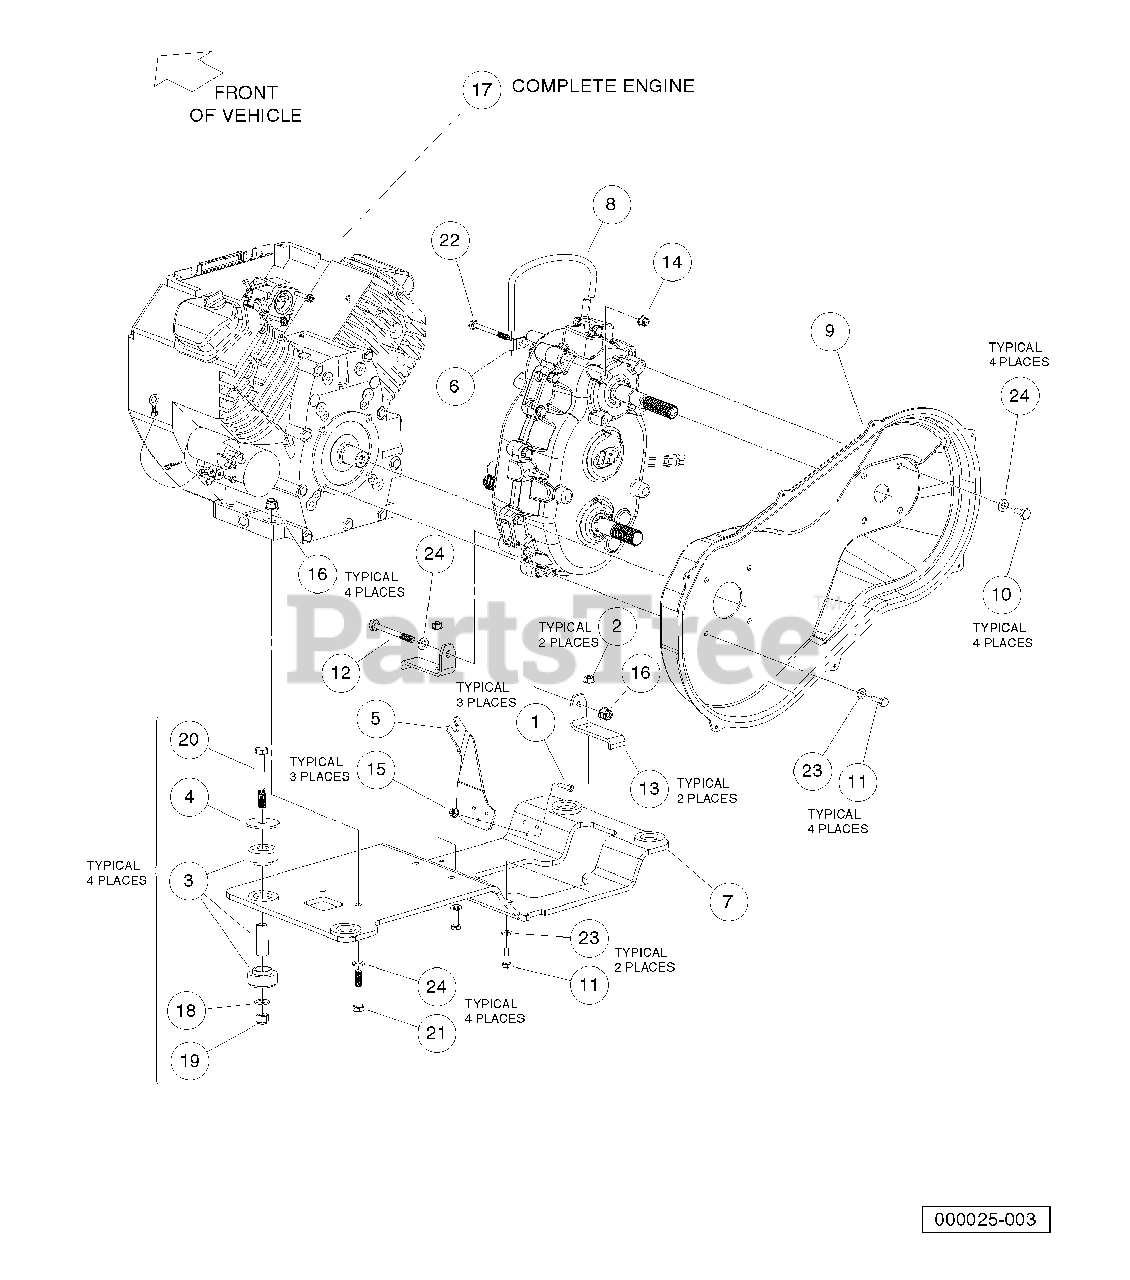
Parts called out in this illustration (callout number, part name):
1	Screw, M6-1.00 X 25mm Hex Cap
2	Nut,m8,all Metal Lock
3	Isolator Ring and Bushing
4	Washer, Snubbing, Ring N Bush
5	Bracket, FNR Trans Cable
6	P-Clamp, Insulated .312 In
7	Plate, Eng Mtg, Weld, Honda
8	Hose, Vent, Transmission
9	Cover, CVT Inner, Honda
10	Bolt, M10 X 1.5 X 20 Loctite
11	Bolt, M8 X 1.25 X 25 Loctite
12	Bolt, M10 X 1.5 X 100 Loctite
13	Bracket, Transmission Mounting
14	Lock Nut, Flg M8 X 1.25 Nylon
15	Nut Flg, M6 X 1.0 Nylon
16	Nut Flg M10 X 1.5 Nylon
17	Engine, Honda, No Acr
18	Washer, M12 Hard
19	Locknut, M12x1.75 Nylon Insert
20	Bolt, M12 X 1.75 X 90
21	Bolt, M10 X 1.5 X 60
22	Bolt, M8 X 1.25 X 80
23	Washer, M8 Hard
24	Washer, M10 Hard
